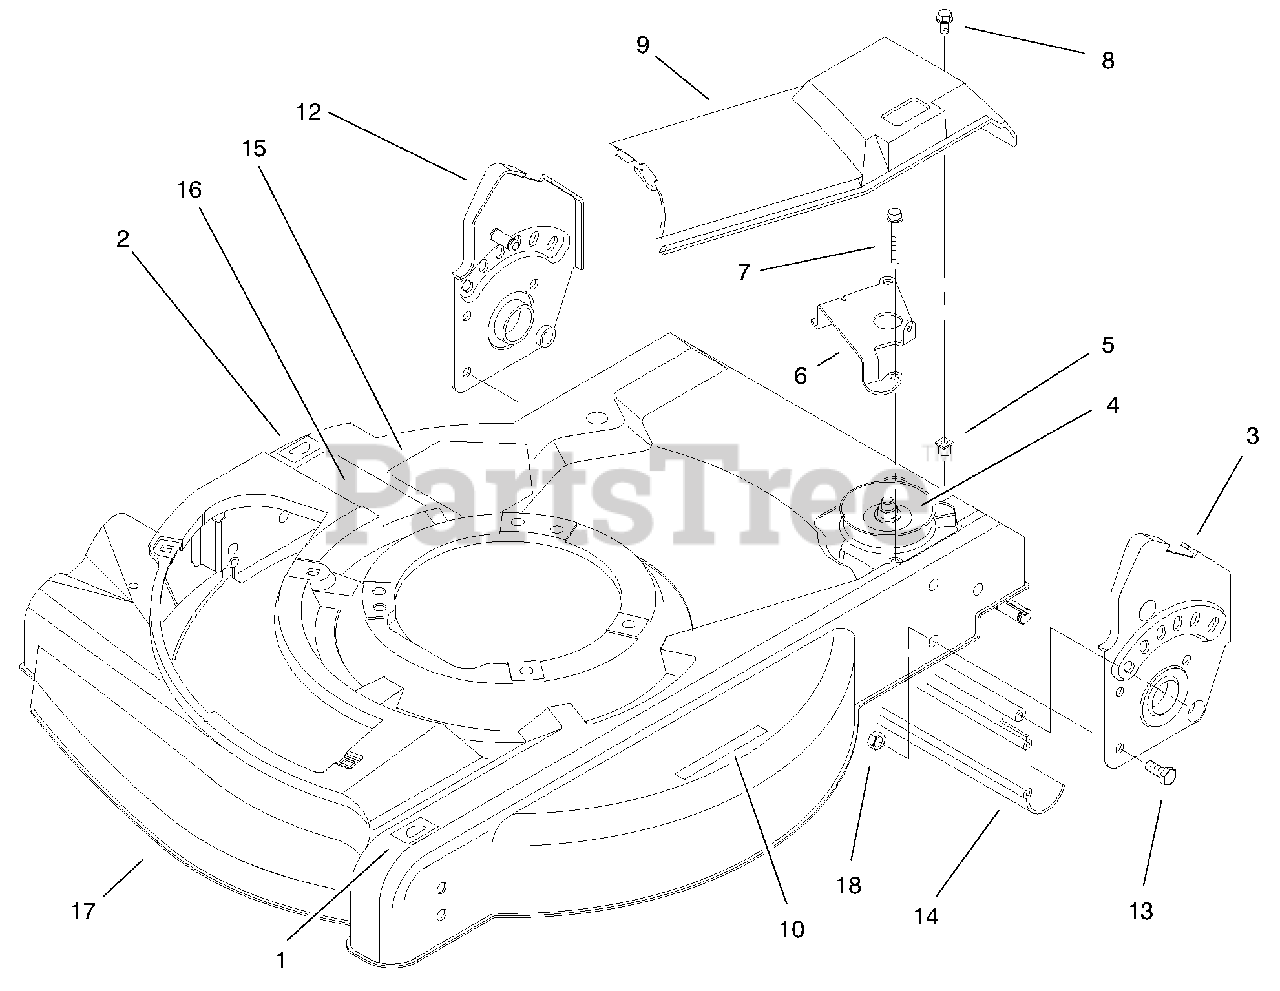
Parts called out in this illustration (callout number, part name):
1	Decal-HOC
2	Decal-HOC
3	ASM-Handle Bracket
4	ASM-Gear Case
5	Grommet
6	Guide-Transmission
7	Screw-Thread Forming
8	Screw-Phil
9	Cover-Drive
10	Decal-Warning
12	ASM-Handle Bracket
13	Screw-HH
14	Shield-Trailing
15	Decal-Danger
16	Decal-Discharge
17	ASM-Housing & Baffle
18	Nut-Lock
